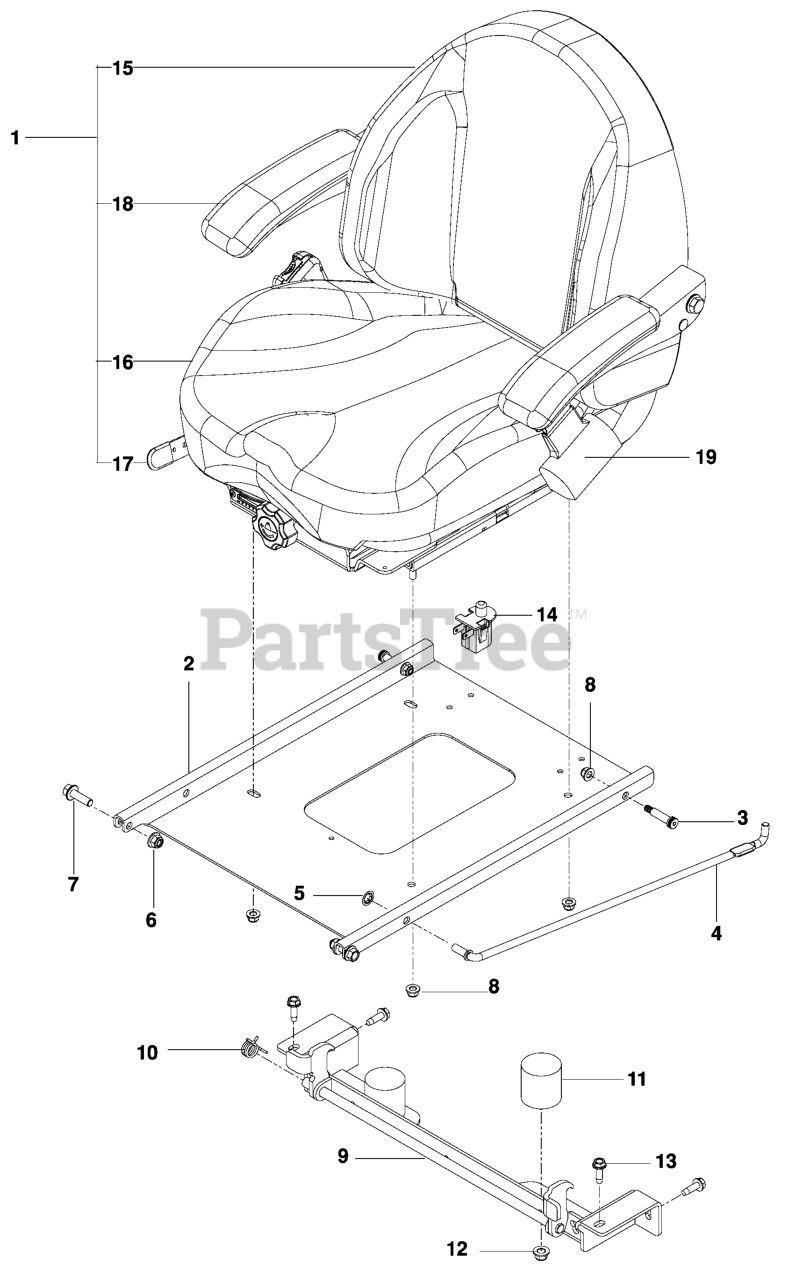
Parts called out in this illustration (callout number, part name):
1	SEAT ASSY
2	PAN, SEAT, BLACK
3	BOLT, SHOULDER 3/8 X 1.25
4	ROD, SEAT
5	NUT 3/8 PALNUT RTNG BLK PHOS
6	NUT 3/8-16 HEX FLG NYLOC ZD
7	HHFS 3/8-16 X 1.25 GD 5
8	5/16-18 NYLOC FLANGE NUT
9	LATCH.SEAT.BLACK
10	SPRING, TORSION
11	BUMPER, RUBBER
12	NUT 3/8-16 HEX FLG NYLOC ZD
13	RP BLT 5/16-18 X 1 THRD FORM D
14	SEAT SWITCH
15	COVER, BACK
16	COVER KIT, CUSHION
18	ARMREST, LT
20	SEAT BELT
